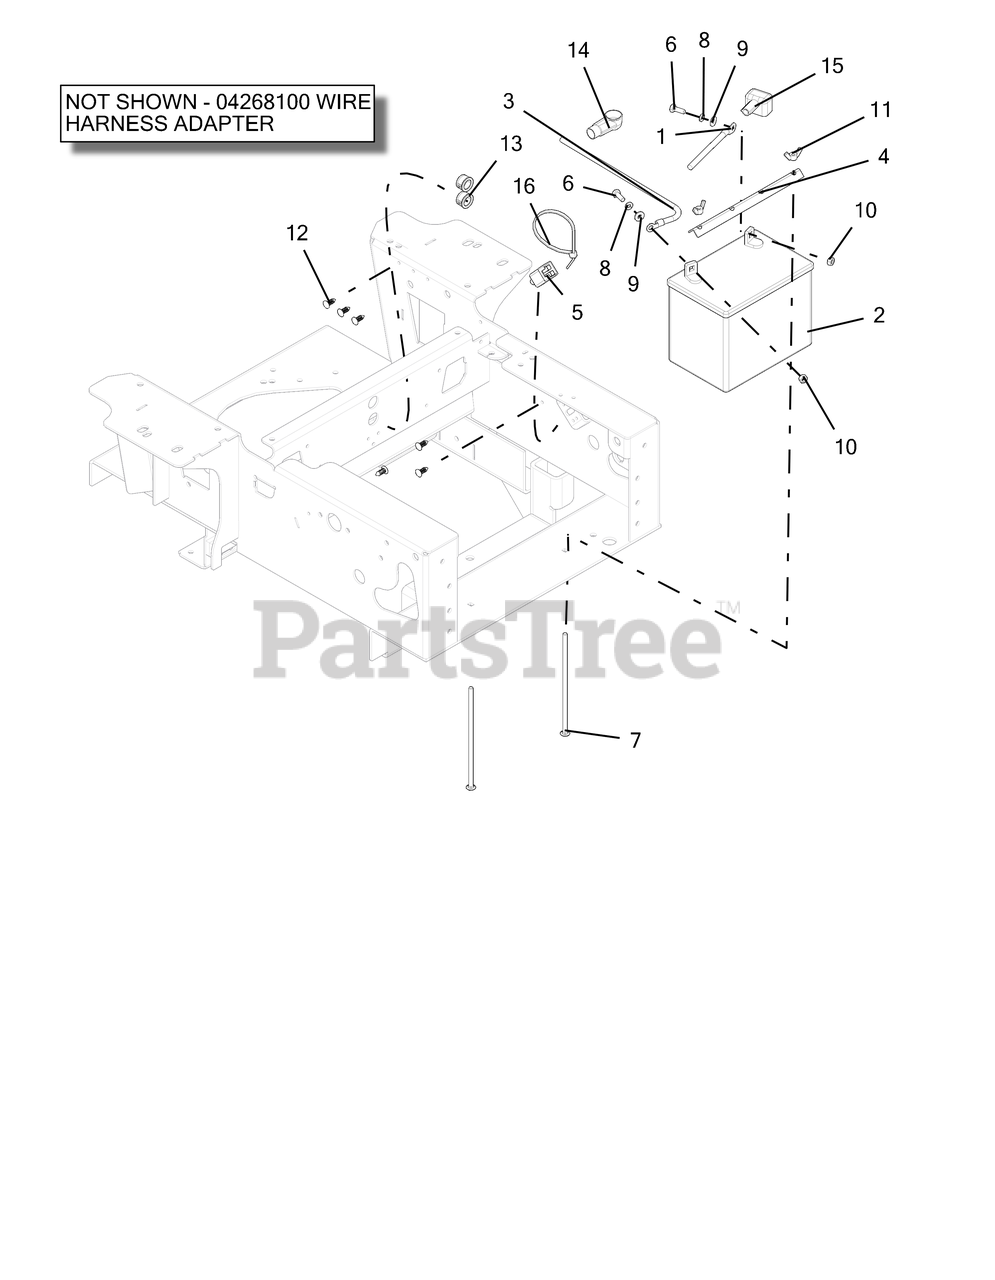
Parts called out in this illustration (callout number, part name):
1	CABLE, POS W/(2) 5/16 RING 30.0 LG
2	BATTERY, 300 CCA 10U1L
3	CABLE, NEGATIVE BATTERY 24"
4	HOLD DOWN - BLK
5	SWITCH, SNAP IN -N.O./N.O
6	BLT-HEX .25-20X.75 GR5 YWZC
7	BLT-RDHDSQNK .25-20X7.50 G2 YWZC
8	WSHR-LK .25X.062 REG YWZC
9	WSHR-FL-STL.281X.62X.065 YWZC
10	NUT-HEX .25-20 YWZC
11	NUT-LOCKING WING 1/4-20
12	RIVET, .25 NYLON PANEL
13	BUSH, PANEL SNAP .687X.875X.56
14	BOOT, .65 ID POS
15	INSULATOR
16	CABLE, TIE 5.50 LG
